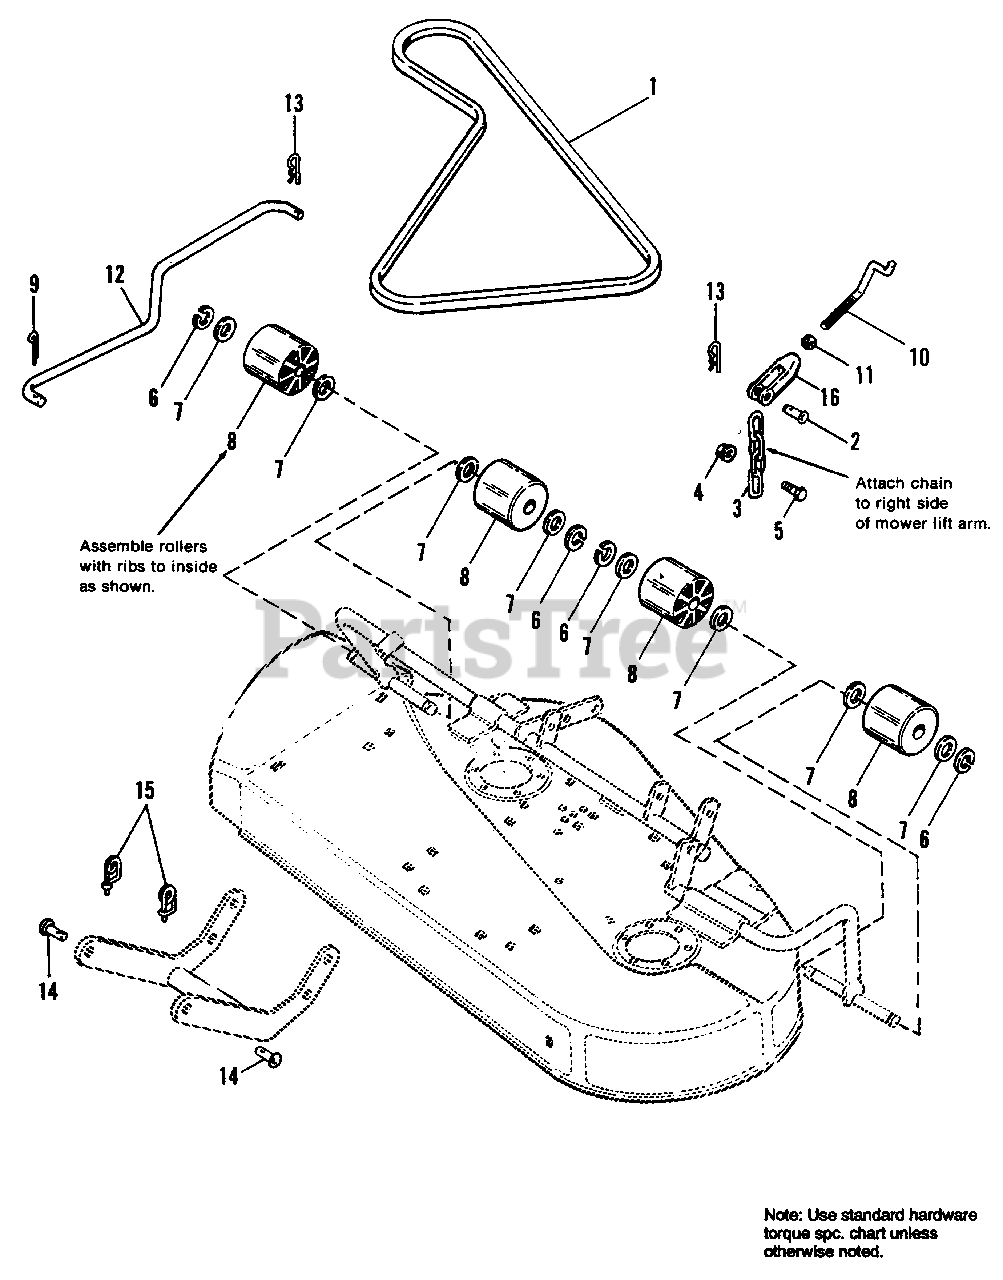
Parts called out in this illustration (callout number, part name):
1	V-BELT, Mower Drive
2	PIN, Rivet
3	CHAIN, Lift 4 Links
4	LOCKNUT, Hex, Flange, 5/16-18
5	CAPSCREW, Hex Hd., 5/16-18 x 1
6	RING, Retaining
7	WASHER, Plain, 5/8
9	PIN, Cotter, 3/32 x 1
11	NUT, Jam, 5/16-18
12	ROD, P.T.O.
13	CLIP, Hairpin
15	CUP, Safety
